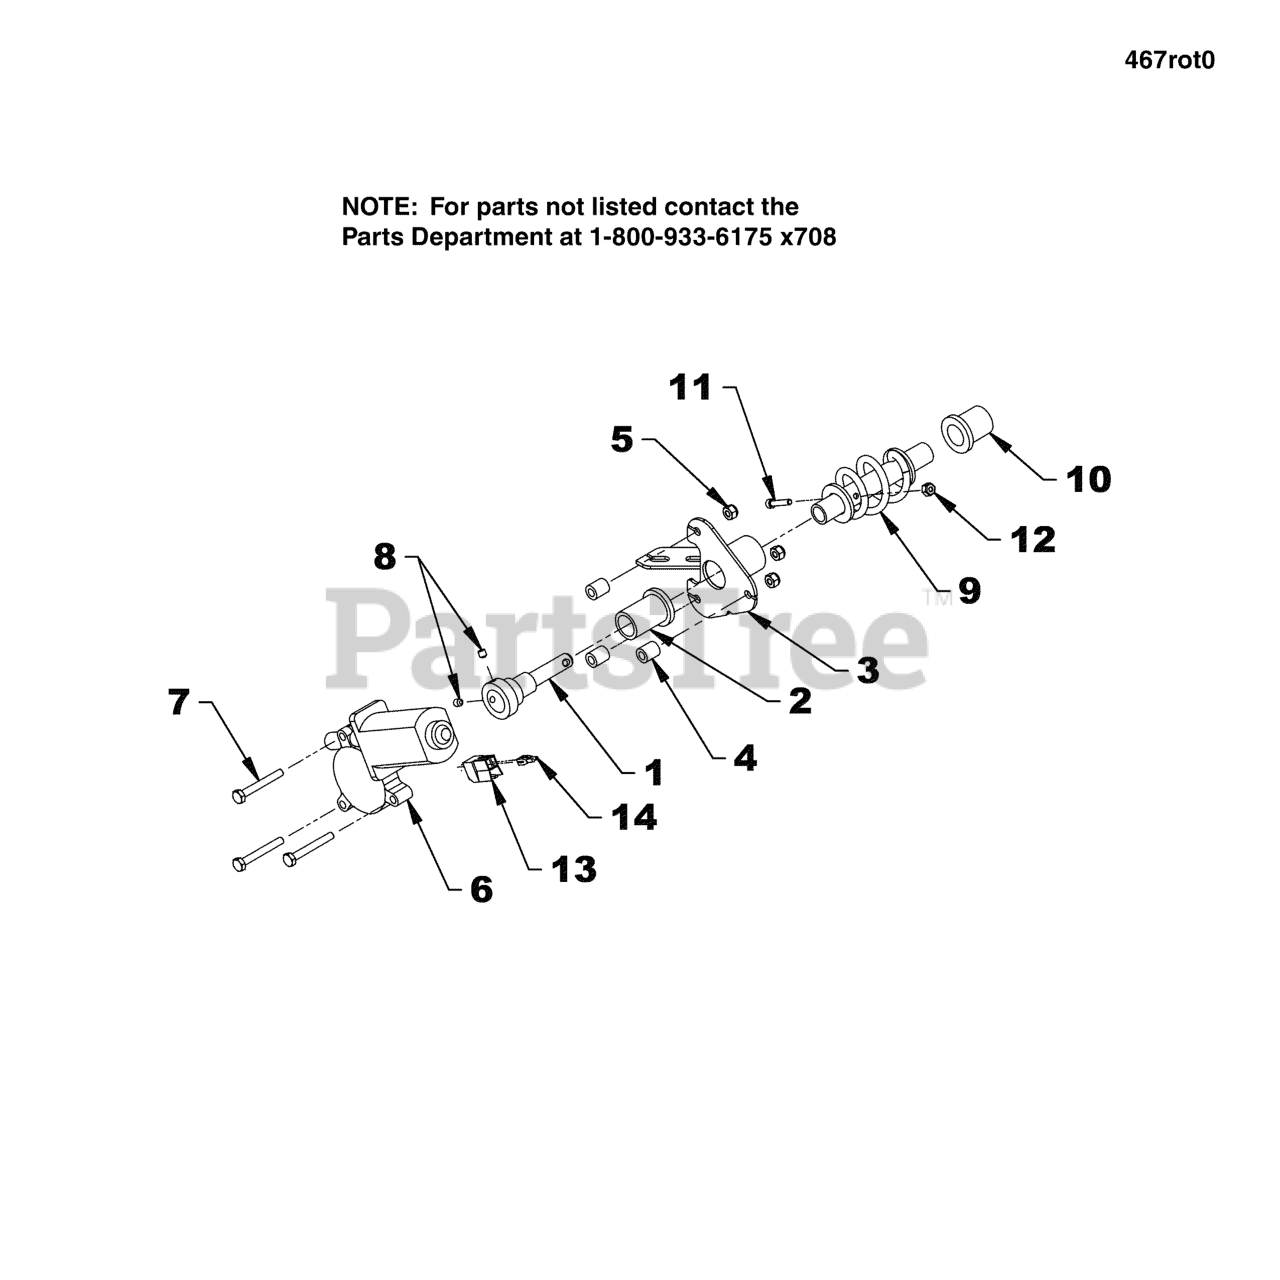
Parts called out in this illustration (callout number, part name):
1	Worm adaptor
2	Plastic bushing 1 11/16" lg.
3	Electric motor support CW
4	Spacer ring
5	Nylon insert nut 1/4" PTD
6	Electric rotation motor
7	Hex bolt 1/4" NC x 2" gr.5 PTD
9	Electric rotation worm PTD
10	Plastic bushing 1 5/16" lg.
12	Nylon insert locknut 10-24 x 1" PTD
13	Female connector
14	Female terminal
